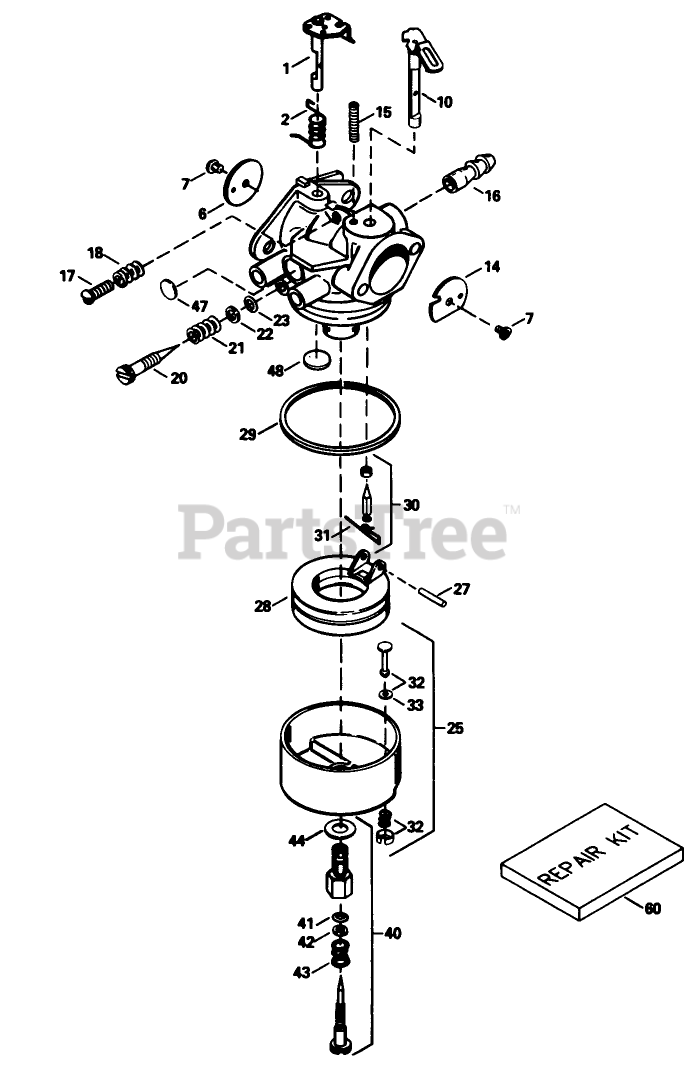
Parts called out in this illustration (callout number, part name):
1	Throttle Shaft and Lever ASM
2	Spring-Return, Throttle
6	Shutter-Throttle
7	Screw-Shutter
10	Choke Shaft and Lever ASM
14	Shutter-Choke
15	Spring-Positioning, Choke
16	Fitting-Fuel
17	Screw-Throttle Crack Screw / Idle Speed
18	Spring-Tension
20	Screw-Idle Mix
21	Spring-Tension
22	Washer
23	ORing
25	Float Bowl Asm. (Incl. Ref. # 32, 33)
27	Shaft-Float
28	Float
29	O Ring-Bowl, Float
30	Inlet Needle, Seat Clip Assy. (Incl. No. 13)
31	Clip-Spring
32	Bowl Drain ASM
33	Gasket-Plunger, Drain
40	Adjustment Screw Assy.,Main (Incl. Ref. #5A,21,23 30)
41	ORing
42	Washer
43	Spring
44	Washer-Bowl Nut
47	Plug-Welch, Idle Mixture Well
48	Plug-Welch, Atmospheric Vent
60	Kit-Repair
